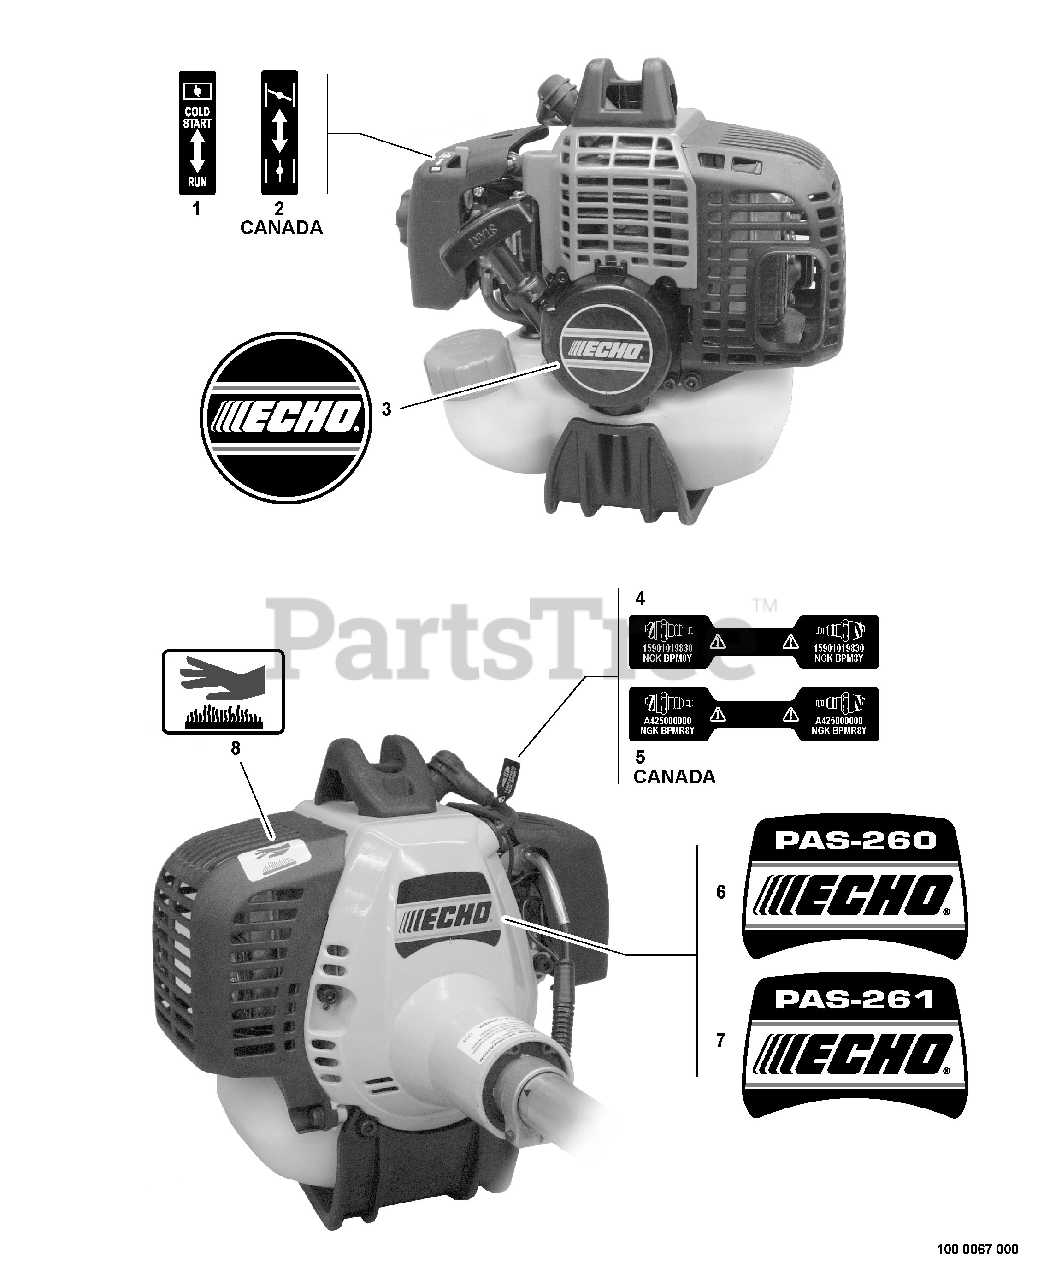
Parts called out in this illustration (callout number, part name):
1	LABEL - CHOKE
2	LABEL - CHOKE
3	LABEL - ECHO
4	LABEL - SPARK PLUG -- BPM-8Y
5	LABEL - SPARK PLUG -- BPMR-8Y
6	LABEL - MODEL PAS-260
7	LABEL - MODEL PAS-261
8	LABEL - HOT SURFACE
